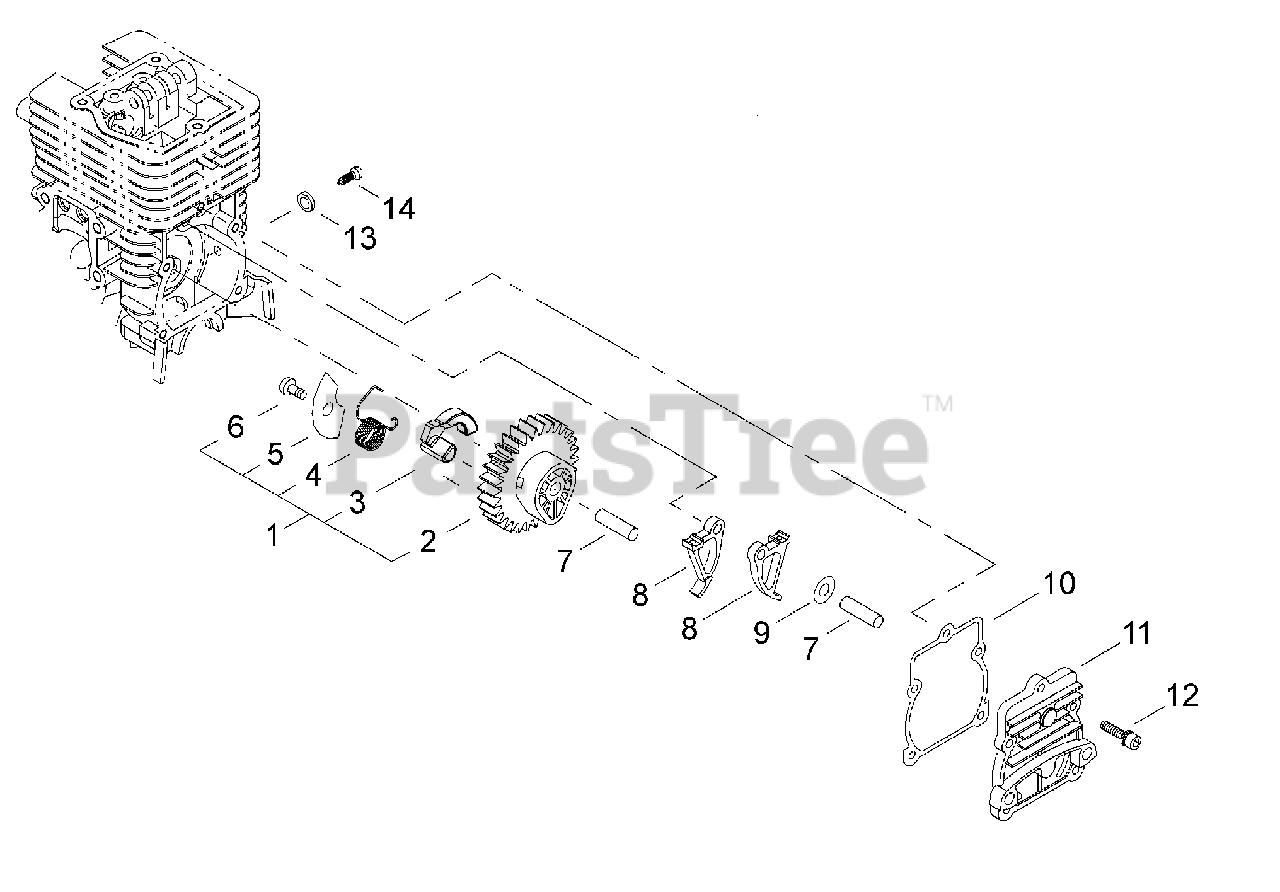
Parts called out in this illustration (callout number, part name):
1	CAM GEAR ASSY
2	GEAR, CAM
3	WEIGHT
4	SPRING
5	COVER, PLATE
6	SCREW - 4X6 -- TAPPING
7	PIN - LOCATING
8	FOLLOWER, CAM
9	WASHER - 5
10	GASKET
11	COVER, CAM GEAR
12	SCREW - 4X14
13	WASHER
14	SCREW - 5
